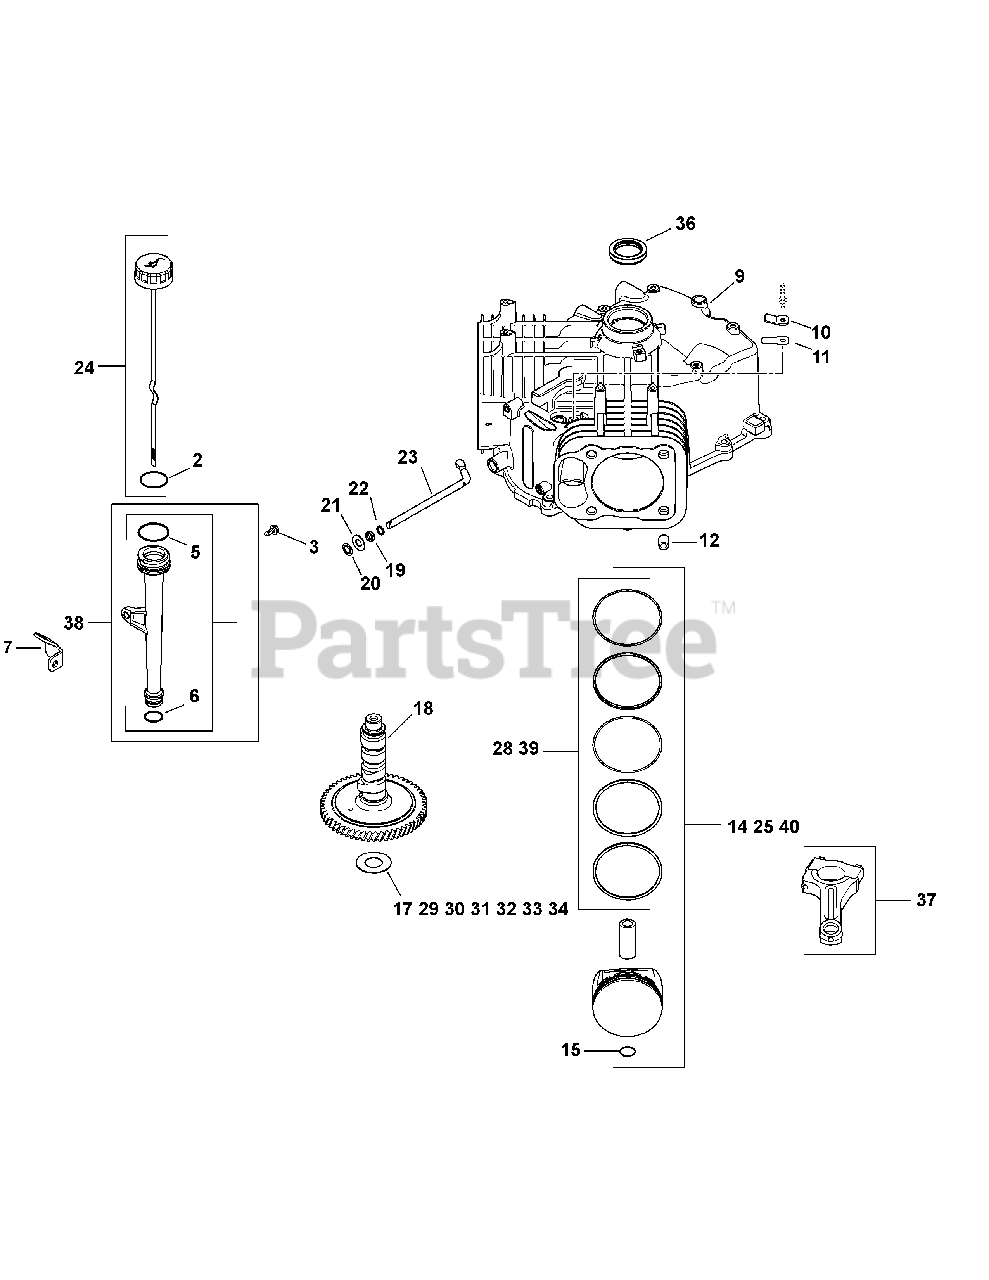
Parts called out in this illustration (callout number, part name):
2	O-ring
3	Flg. Thd. Frm. Screw, M5 X 0.8 X 13
5	O-ring, Upper Fill Tube
6	O-ring, Lower Fill Tube
7	Oil Fill Tube Bracket
10	Breather Reed Retainer
11	Breather Reed
14	Piston Kit w/ Ring Set
15	Piston Pin Retainer
17	Camshaft Shim (White .028")
18	Camshaft Kit
19	Governor Cross Shaft Seal
20	Ring Retainer
21	Flat Washer, 9 Mm
22	Flat Washer, 11.32
23	Governor Cross Shaft
24	Dipstick Assembly
25	Piston Kit w/ Ring Set (0.25) 83mm
28	Ring Set (.25)
29	Camshaft Shim (Blue .03")
29	Camshaft Shim (Red .032")
29	Camshaft Shim (Yellow .034")
29	Camshaft Shim (Green .036")
29	Camshaft Shim (Gray .038")
29	Camshaft Shim (Black .04")
36	Oil Seal (Helix Lip)
37	Connecting Rod (Std)
38	Tube Assembly
39	Ring Set (Std)
40	Ring Set
